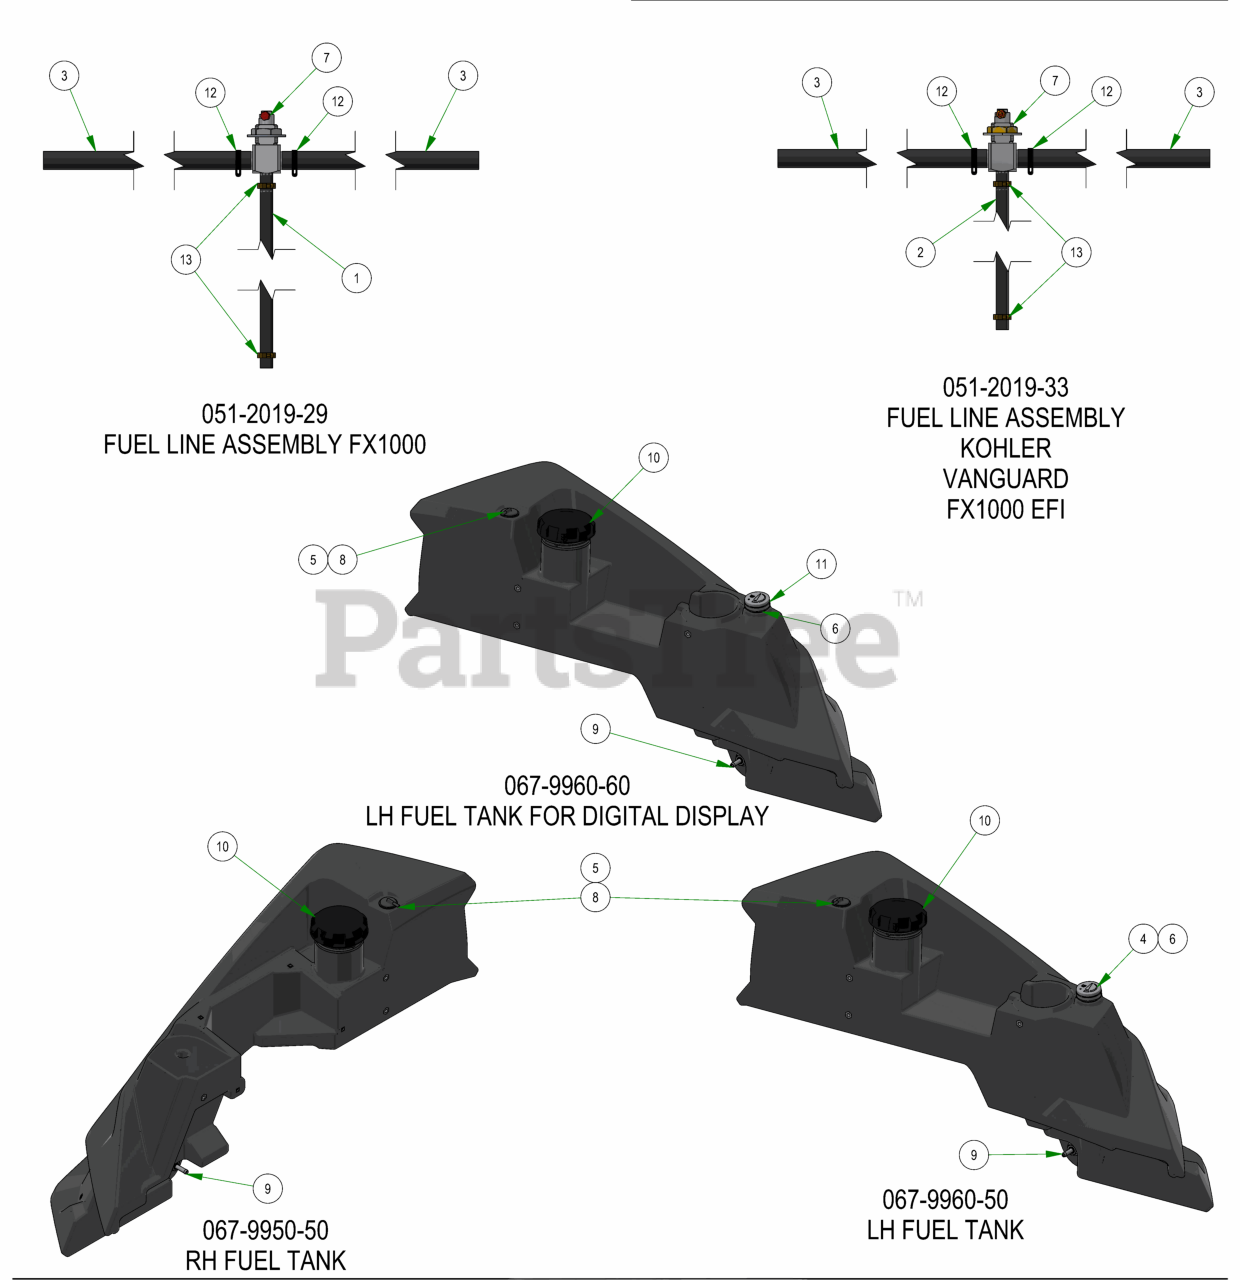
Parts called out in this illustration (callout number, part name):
1	1/4" Fuel Line Hose
2	1/4" Fuel Line Hose
3	5/16" fuel line hose
4	Fuel Gauge with Grommet
5	Roll Over Valve Grommet
6	Fuel Gauge Grommet
7	3 Way Fuel Shut-Off Valve 5/16 x 5/16 x 1/4
8	Rollover Valve
9	Fuel Pick-up
11	Electronic Fuel Gauge
12	5/16 Fuel Line Clamp
13	1/4 Fuel Hose Clamp
